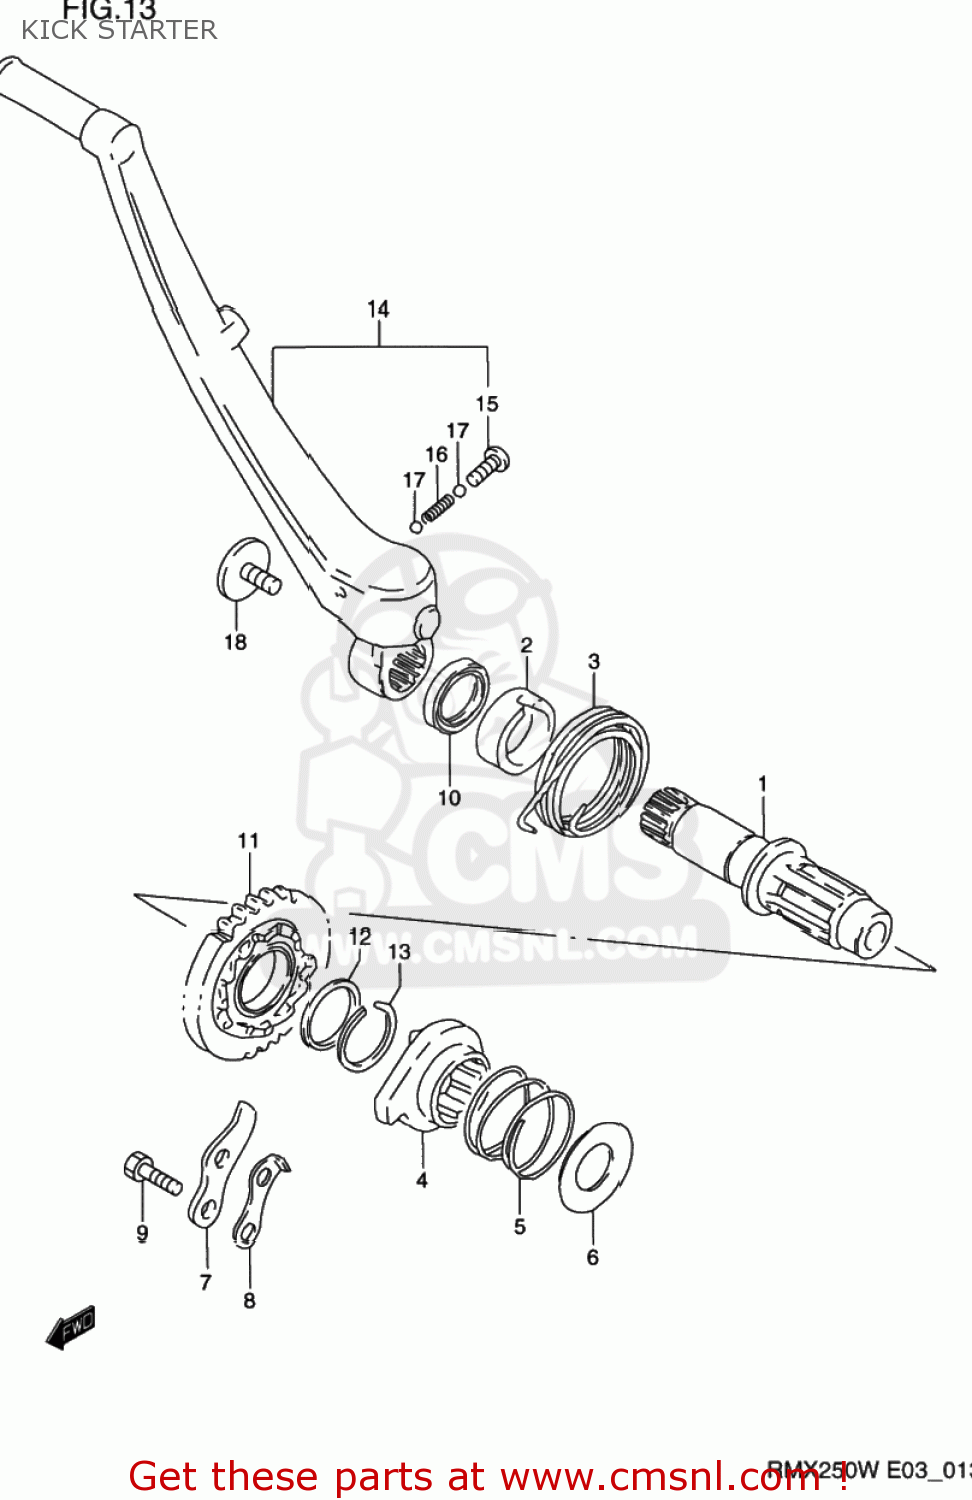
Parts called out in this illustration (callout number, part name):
1	SHAFT,KICK STARTER
2	GUIDE,KICK STARTER SHAFT
3	SPRING
4	STARTER,KICK
5	SPRING
6	WASHER
7	GUIDE,KICK STARTER
8	STOPPER,KICK STARTER
9	BOLT
10	SEAL,OIL(20X27X5)
11	GEAR,KICK STARTER DRIVE(NT:30)
12	SHIM(22X28X1)
13	CIRCLIP
14	LEVER ASSY,KICK STARTER
15	SCREW(6X27.5)
16	SPRING
17	BALL
18	BOLT(8X14)
